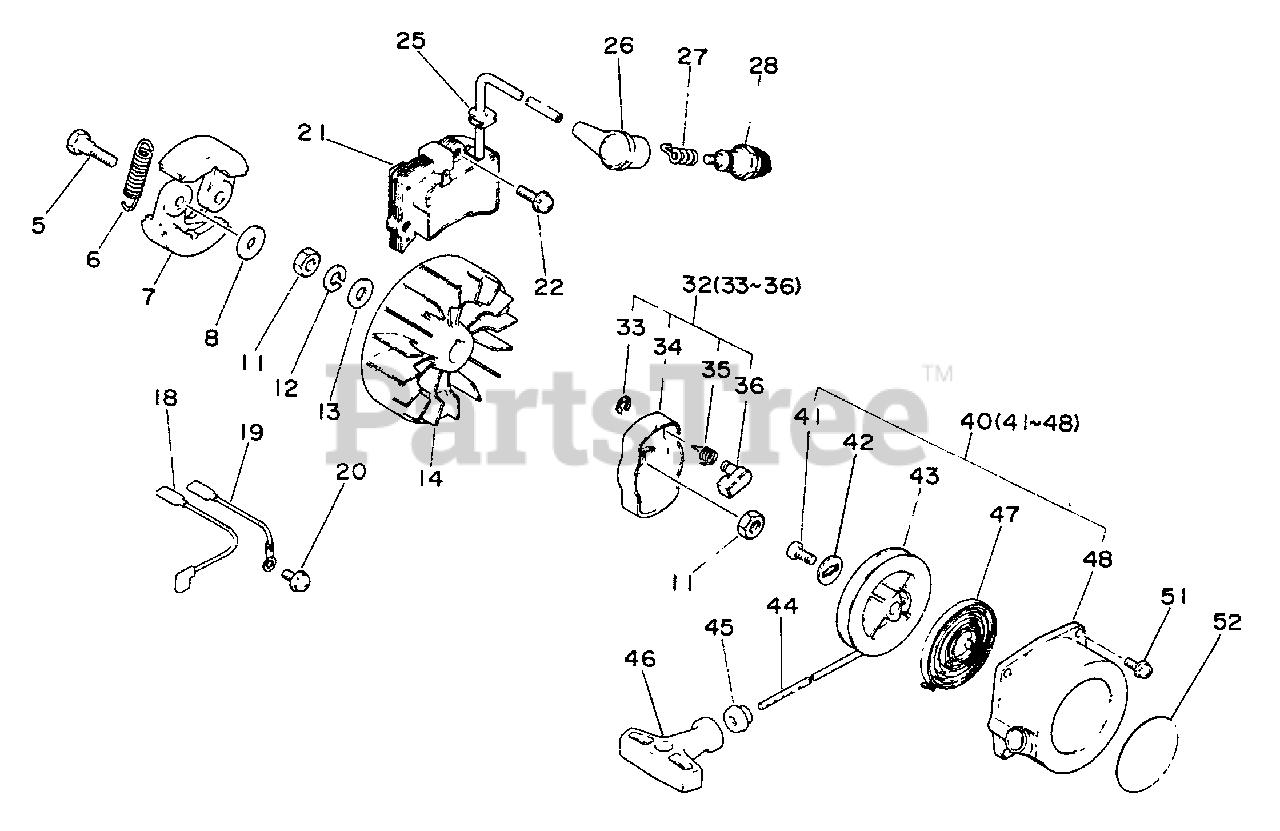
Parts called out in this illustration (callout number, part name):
5	BOLT, CLUTCH
6	SPRING, CLUTCH
7	SHOE, CLUTCH
8	WASHER - 6
12	LOCKWASHER - 8
13	WASHER - 8
14	FLYWHEEL
18	LEAD
19	LEAD - GROUND
20	SCREW - 5X10
21	COIL, IGNITION
22	SCREW - 5X20
26	CAP, SPARK PLUG
27	TERMINAL, SPARK PLUG CAP
28	SPARK PLUG -- CJ-7Y
32	STARTER PAWL ASSY
33	RING, RETAINING - 6
34	CATCHER, PAWL
35	SPRING, RETURN
36	PAWL, STARTER
40	STARTER ASSY
42	WASHER
43	REEL, ROPE
44	ROPE, STARTER - 3.5X850
45	GUIDE, ROPE
46	GRIP, STARTER
47	SPRING, REWIND
48	CASE, STARTER
51	SCREW - 4X14
52	LABEL - ECHO
